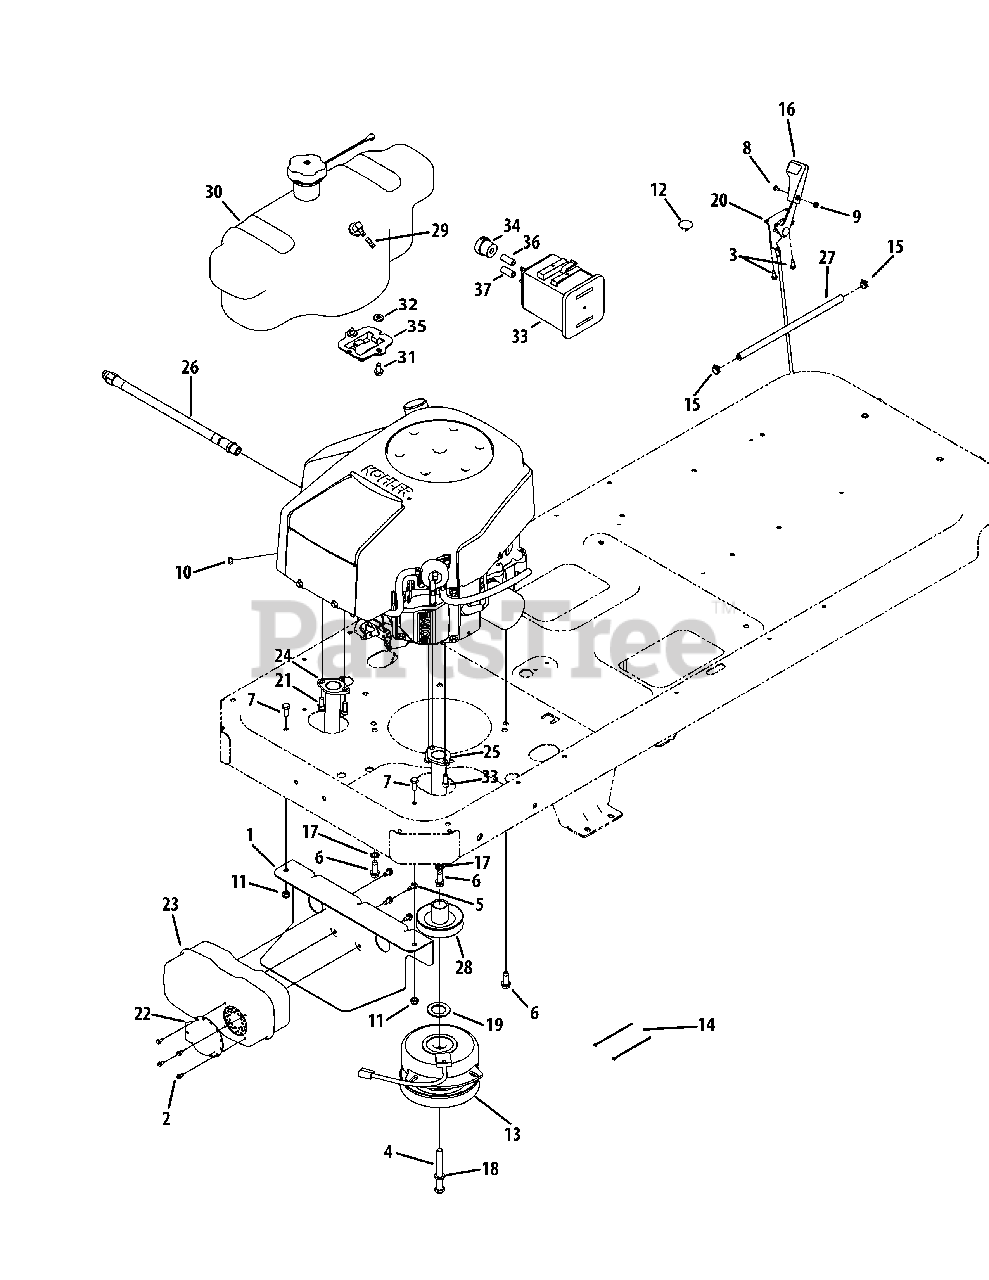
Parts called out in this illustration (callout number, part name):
1	Muffler Mount Bracket
2	Hex Washer Screw, #8-18 x .500
3	Screw, 1/4-14 x .625
4	Hex Lock Screw, 7/16-20 x 3.50
5	Hex Washer Screw, 1/4-20 x .500
6	Hex Washer Screw, 3/8-16 x 1.000
7	Hex Washer Screw, 5/16-18 x .75
8	Machine Screw, #8-32 x .375
9	Hex Nut, #8-32
10	Sems Nut, 1/4-20
11	Flange Lock Nut, 5/16-18
12	Choke Plug
13	Electric PTO Clutch
14	Cable Tie
15	Hose Clamp
16	Throttle Control Knob
17	Lock Washer, 3/8
18	Lock Washer, 7/16
19	Flat Washer, 1.03 x 1.620 x .095
20	Throttle/Choke Control Cable
21	Screw, 5/16-18 x .750
22	Muffler Deflector
23	Dual Inlet Muffler
24	Exhaust Pipe, LH
25	Exhaust Pipe, RH
26	Oil Drain Hose
27	Fuel Hose
28	Engine Pulley
29	Hose Vent, 3/16 EPA
30	Fuel Tank Assembly
30	Fuel Tank Bushing
30	Rubber Grommet
30	Fuel Pick-Up Fitting
30	Fuel Cap
30	Rollover Valve
31	Screw 5/16-18 x .875
32	Washer, Flat, .344 x .750 x .120
33	Canister, Carbon, 5 Gallon
34	Filter, Vent, Canister
35	Bracket., Adapter, Canister
36	Hose, Fuel, Low Perm., White
37	Hose, Fuel, Low Perm., Yellow
